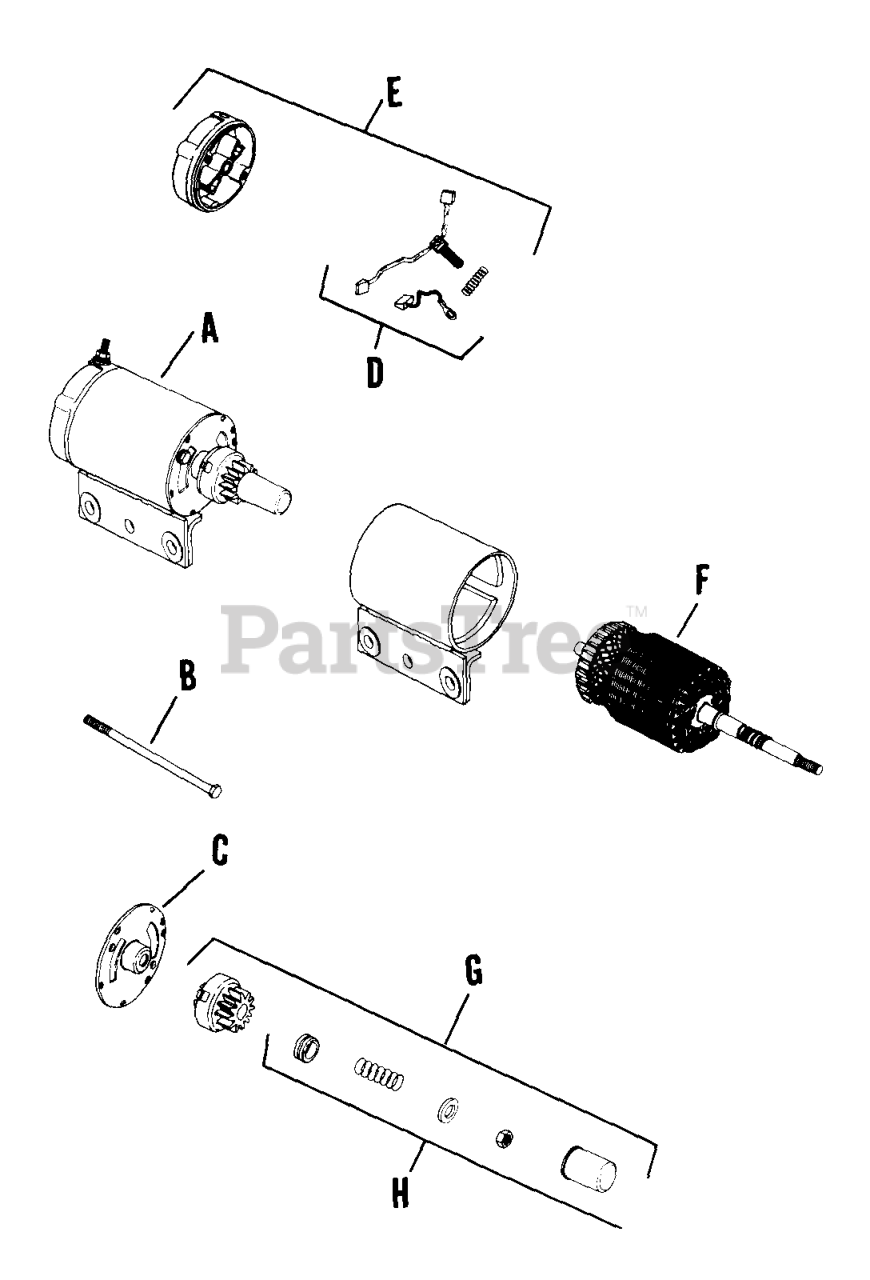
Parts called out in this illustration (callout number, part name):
A	STARTER - USE 45 098 05
C	CAP - USE 45 081 05
D	KIT - USE 52 755 15
E	CAP - DISCONTINUED
F	KIT, ARMATURE - DISCONTINUED
G	STARTER - USE 45 098 09
